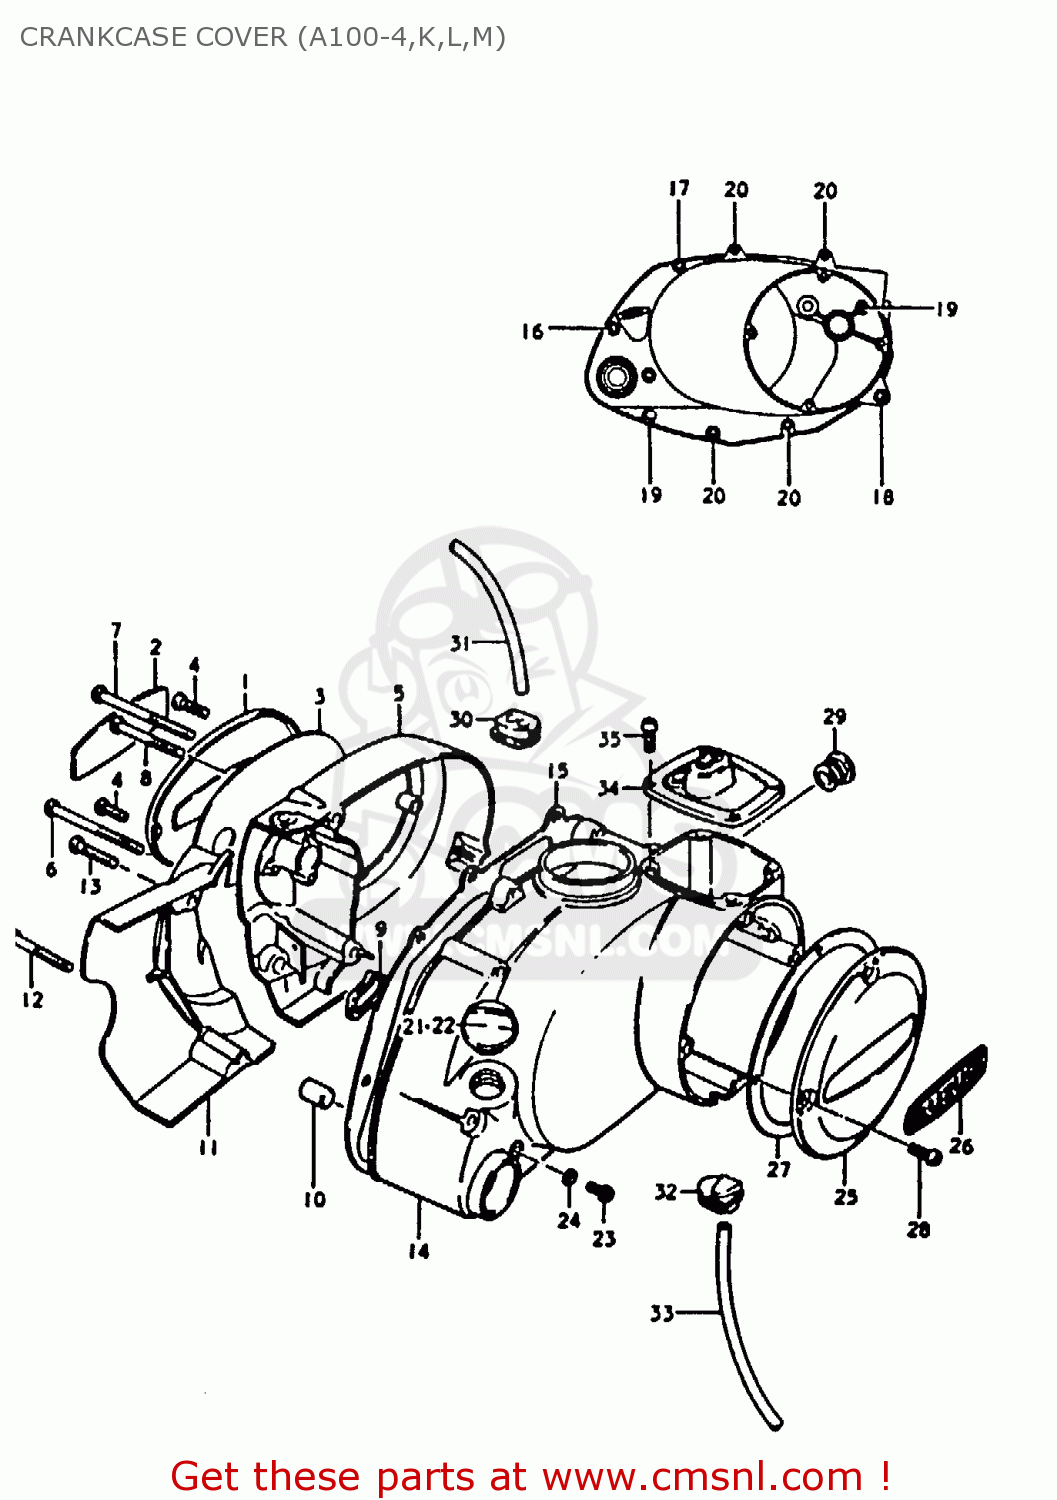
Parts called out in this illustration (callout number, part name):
1	CAP,MAGNETO INSPECTION
2	EMBLEM,CONTACT BREAKER CAP
3	GASKET
4	SCREW
5	COVER,MAGNETO
6	SCREW 6X65
7	SCREW
8	SCREW
9	CAP,MAGNETO COVER SEAL
10	PIN
11	COVER,SPROCKET
12	SCREW (6X45)
13	SCREW
14	COVER,CLUTCH
15	GASKET,CLUTCH COVER (MCA)
16	SCREW 6X70
17	SCREW
18	SCREW (6X45)
19	SCREW (6X35)
20	SCREW
21	PLUG,OIL FILTER
23	SCREW(6X10)
24	GASKET(6.2X11X1) (NAS)
25	CAP,CARBURETOR INSPECTION
26	EMBLEM,CONTACT BREAKER CAP
27	GASKET (MCA)
28	SCREW
29	Plug
30	GROMMET
31	HOSE
32	GROMMET
33	HOSE
34	COVER,CARBURETOR,TOP
35	SCREW
